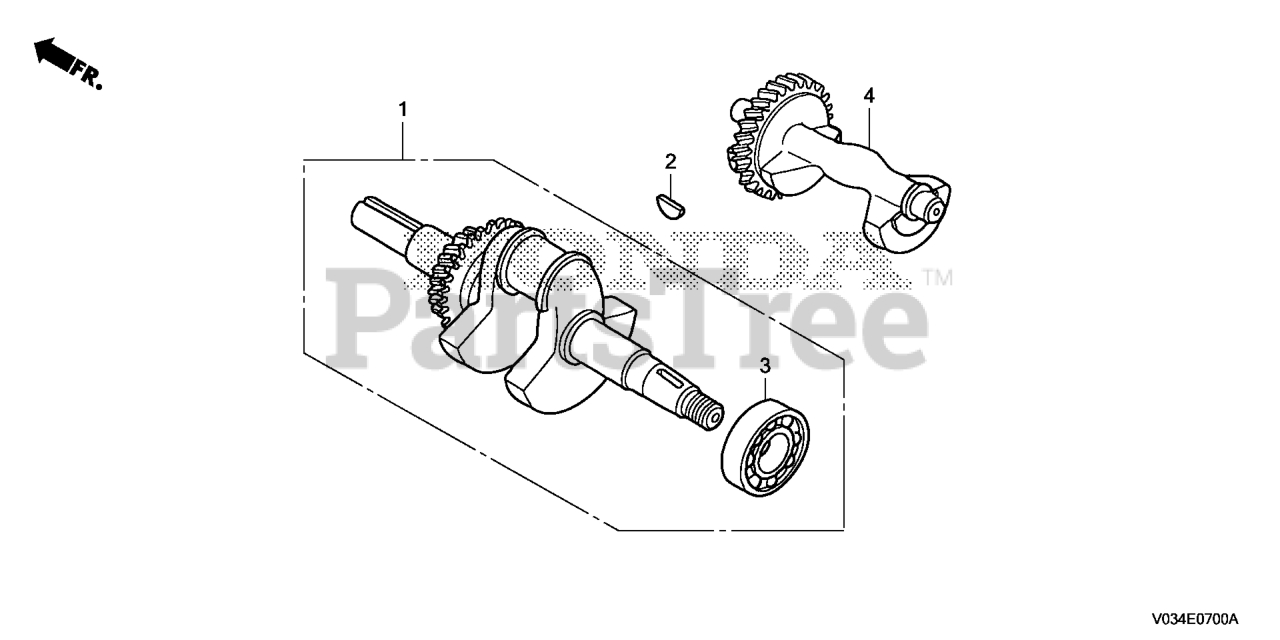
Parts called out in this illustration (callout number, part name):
1	CRANKSHAFT
2	KEY, SPECIAL WOODRUFF (25X18)
3	BEARING, RADIAL BALL (6207)
4	WEIGHT, BALANCER
